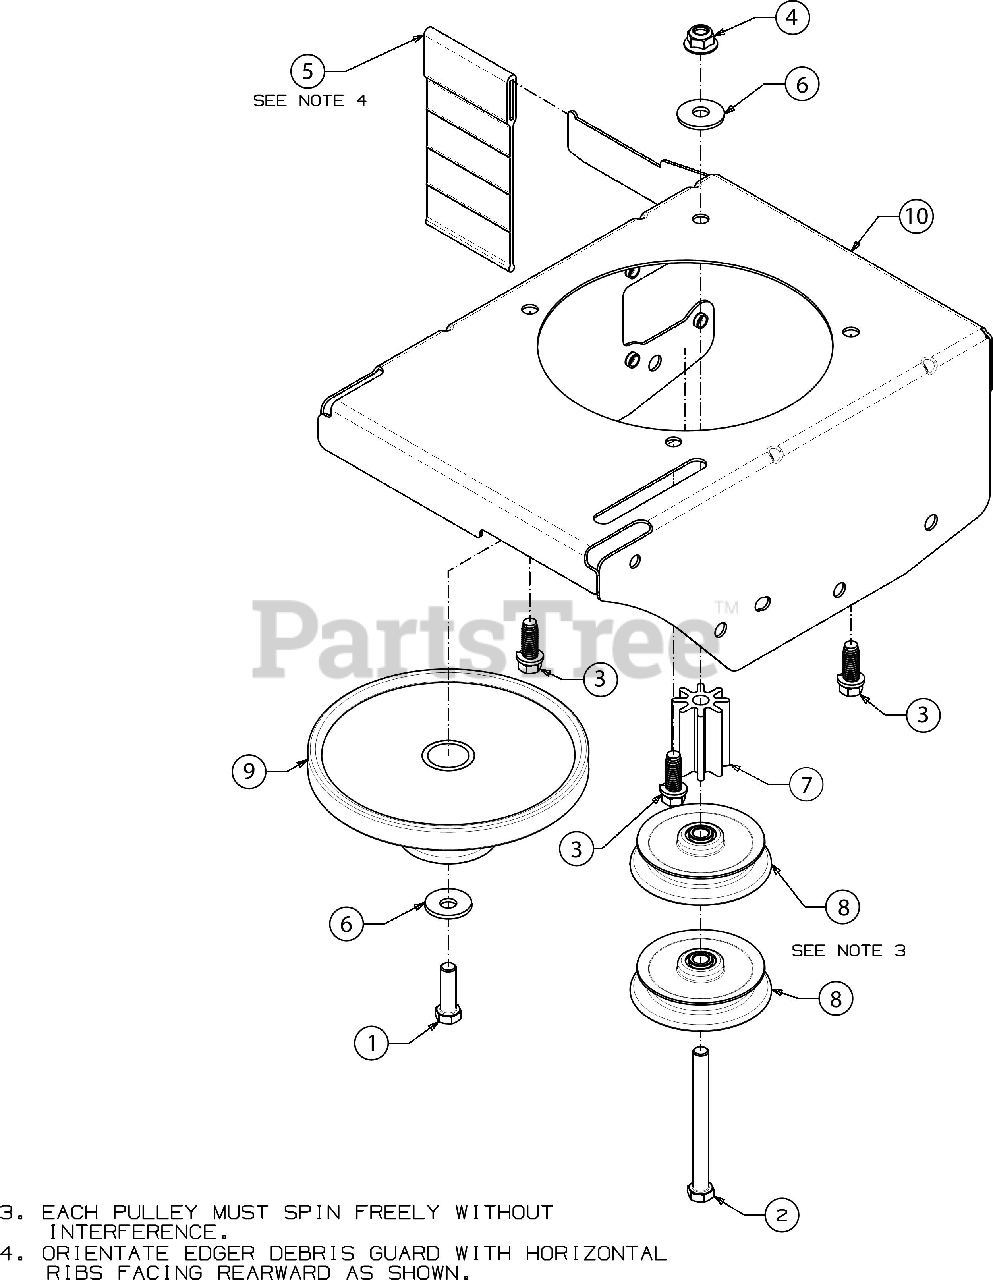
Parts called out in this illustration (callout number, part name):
1	SCREW 3/8-24X1.25
2	HEX SCREW 3/8-16 x 4.00
3	SCREW 3/8-16 x 1
5	EDGER BLADE GUARD
6	BELL WASHER
7	MOUNT SPACER
8	FLAT IDLER PULLEY
9	FLYWHEEL PULLEY
